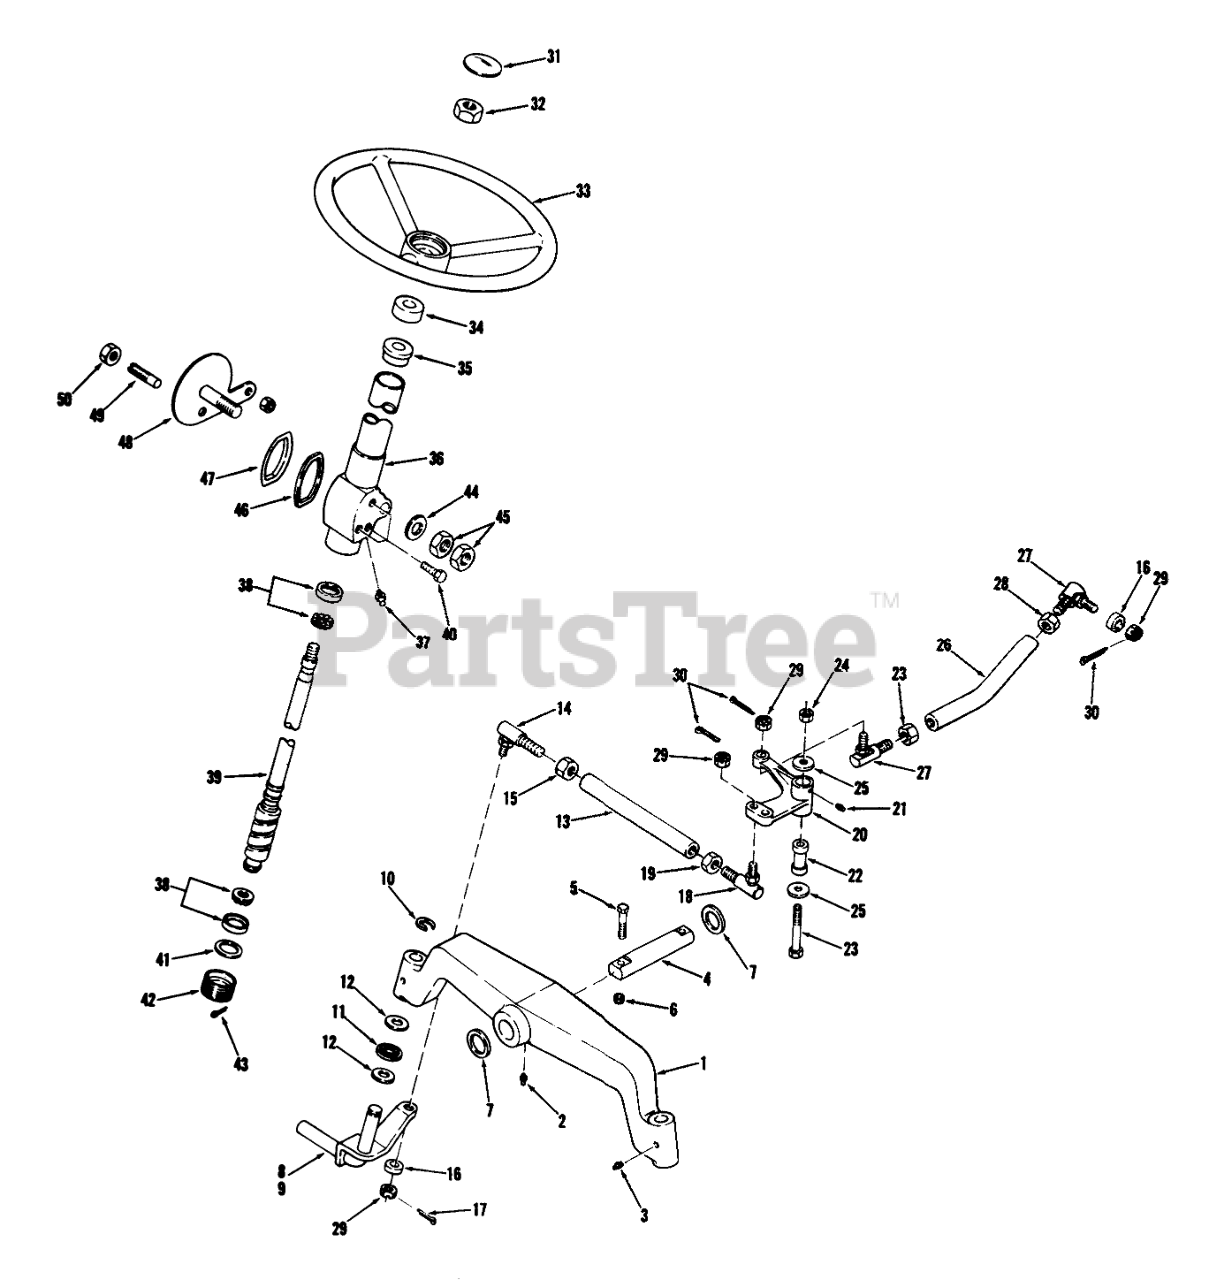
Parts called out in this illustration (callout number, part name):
1	Axle Front
2	FITTING-GREASE
3	Zerk
4	PIN AXLE
6	Nut
7	Washer
8	Spindle Assembly R.H.
9	ASSY-SPNDLE&STEER R
10	E RING
11	BEARING-THRUST
12	WASHER-THRUST
13	TIE ROD R
14	Ball Joint RH
15	NUT-6
16	Washer
18	LH BALL JOINT R
19	Jam Nut LH 1/2-20
20	Bellcrank-steering
21	Zerk
22	Bushing
23	HEX HD CAP SCREW
24	Nut
25	Washer
26	Drag Link
27	BALL JOINT-SHORT R
28	NUT-6
29	Slot Nut 3/8-24
31	STEERING WHEEL INSE
32	Nut
33	Steering Wheel
34	Cover-Dust
35	Column Bearing
36	Assy-Housing and Column
37	Fitting-Grease
38	BALL CUP KIT
39	Steering Gear
40	BOLT
41	WASHER
42	Adjusting Plug
43	Cotter Pin
44	Washer 49/64 X 1 1/4
45	Nut
47	Retainer-Seal
48	Lever
49	Stud
50	Nut
